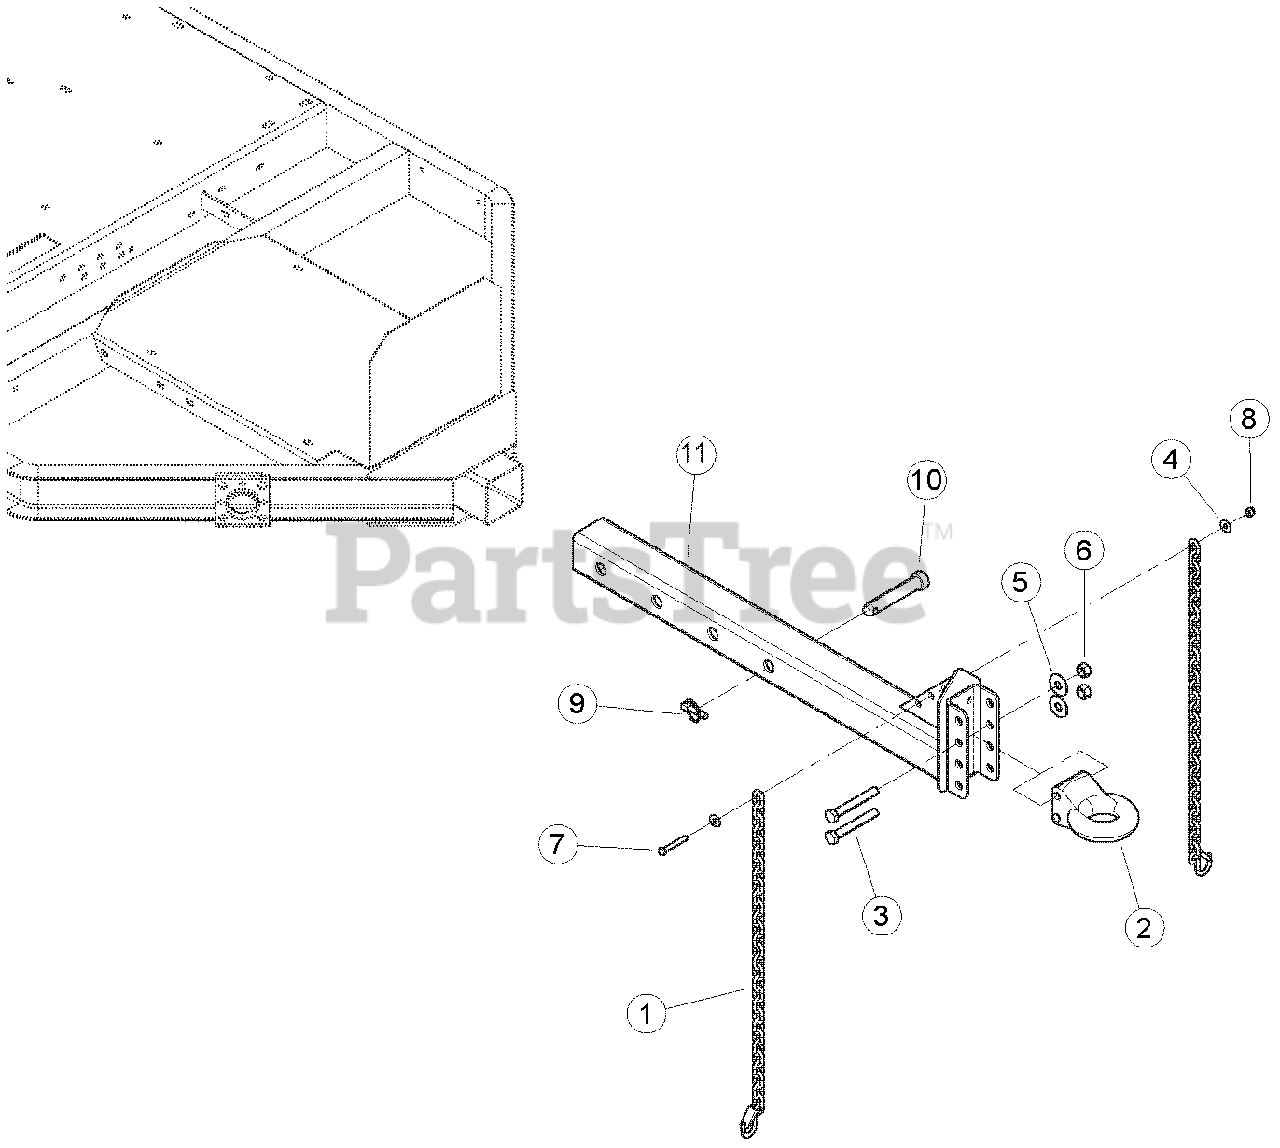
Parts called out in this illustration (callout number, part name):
1	CHAIN, SAFETY 5000 LB W/LATCH
2	HITCH, PINTLE RING, 20,000 LB
3	BOLT, 5/8 X 4-1/2 HEX HD G5 ZP
4	WASHER, 3/8" FLAT ZP (67PCS/LB)
5	WASHER, 5/8" FLAT ZP-37PCS/LB
6	NUT, 5/8" CENTERLOCK ZP GR5
7	BOLT 3/8 X 2-1/2 GR5 HHCS ZP
8	NUT, 3/8" NE NYLOCK ZP
9	PIN, 7/16 X 1-3/4 LYNCH
10	TOP LINK PIN, CAT 2
11	WELDMENT, HITCH POLE W/PLATE
